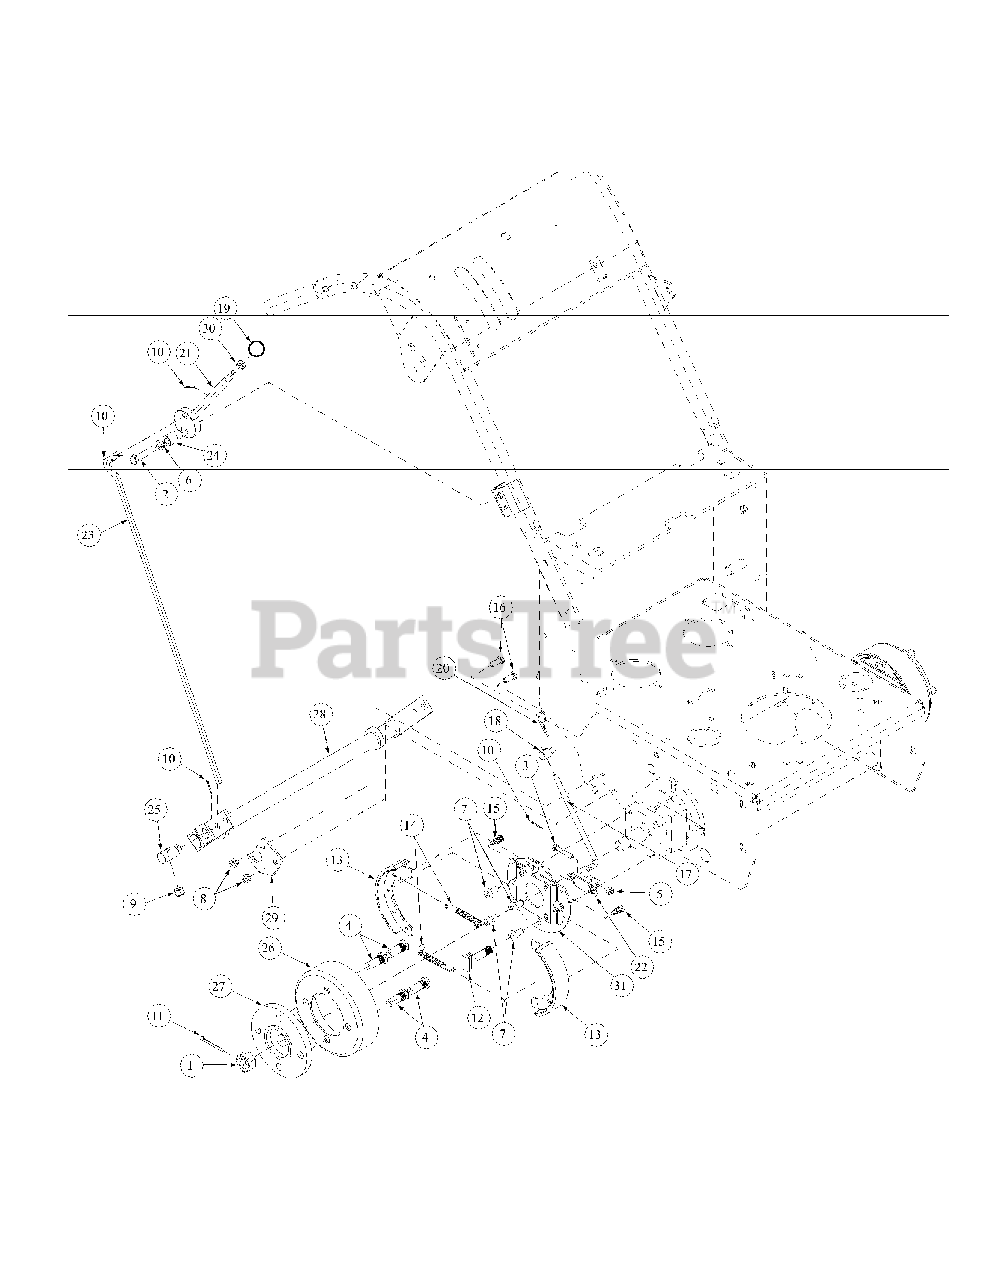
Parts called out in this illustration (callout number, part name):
1	Nut, Castle, 3/4-16
2	Capscrew, 3/8-16 x 1-3/4" Zinc
3	Cap Screw, 1/4-20 x 1.50, Grade 5
4	Bolt, Wheel, 1/2-20 x 1-3/8
5	Lock Nut, Nylon Insert, 1/4-20 Grade A 2
6	Lock Washer, 3/8 Zinc
7	Capscrew, Socket Button Hd., 3/8-16 x 3/4 Zinc
8	Nut, 5/16-18, Nylock
9	Nut, Nylon Insert, 3/8-16 Grade A
10	Cotter Pin, 3/32 x 3/4, Zinc
11	Cotter Pin, 5/32 x 1-1/2 Zinc
12	Brake Cam, Actuating
13	Brake Shoe w/Lining, 6 x 1-1/4
14	Brake Spring, Tension
15	Brake Spring, Anti-Vibration
16	Cap Screw, 5/16-18 x 3/4, Grade 5
17	Brake Rod
18	Swivel Joint
19	Red Knob, Shift w/Insert
20	Hair Pin 3/8"-1/2"
21	Lever Assembly, Brake
22	Brake Clamp, Control Assembly Hydro
23	Rod, Long Brake, Hydro WB
24	Pivot Spacer, Hydro WB
25	Brake Pull Joint
27	Hub, Wheel Motor
28	Brake Pivot Shaft Assembly
29	Pivot Mount, Brake
30	Nut, 3/8-16, Jam, Grade 2
31	Brake Backing Plate
